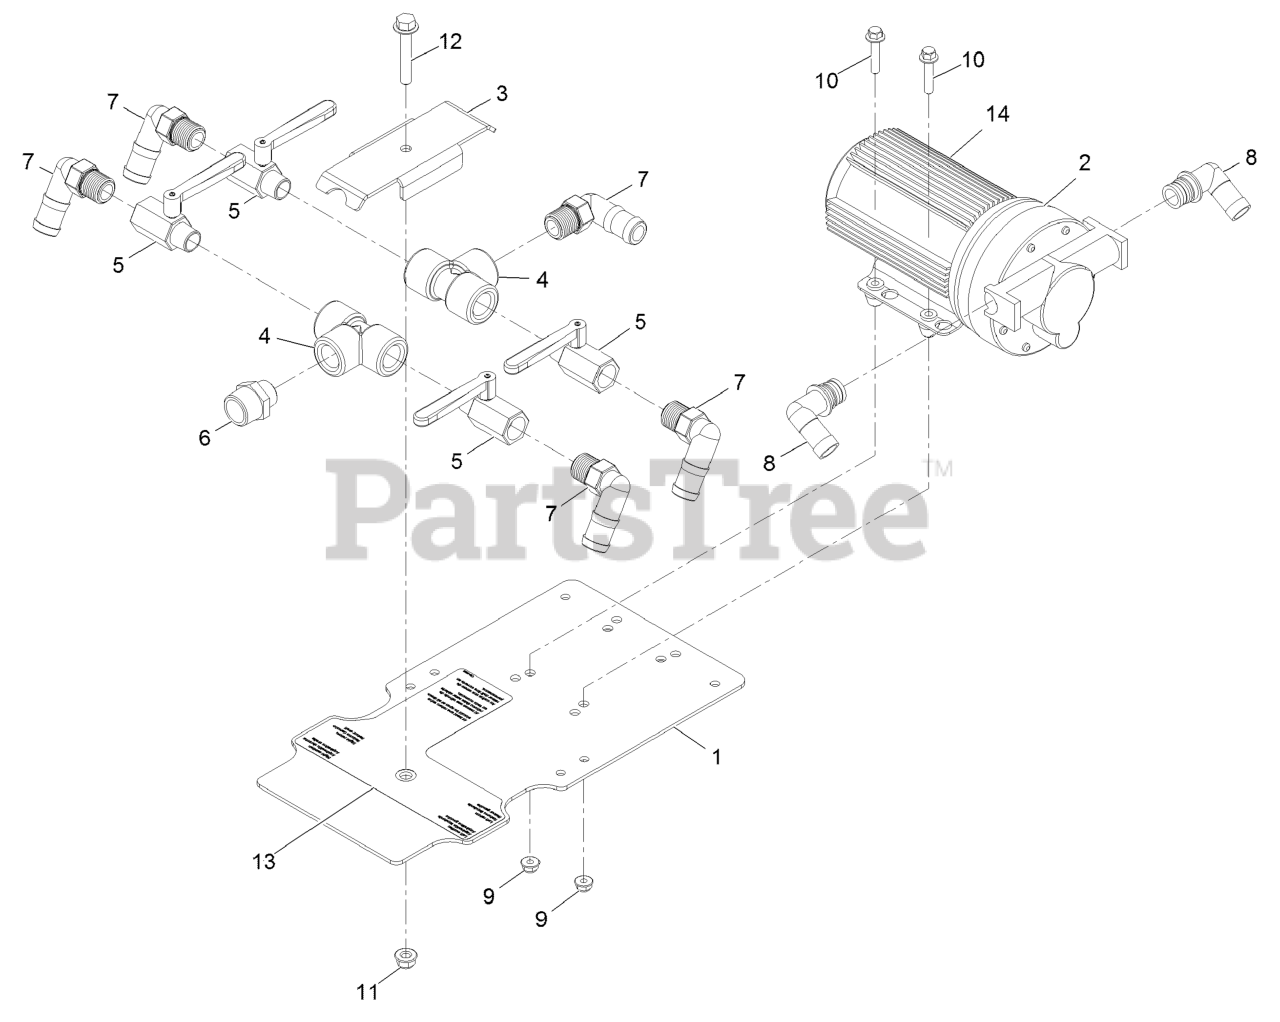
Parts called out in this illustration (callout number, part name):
1	MOUNT-PLATE, LIQUID VALVE
2	PUMP-5.3 GPM
3	PLATE-CLAMP, LIQUID VALVE
5	VALVE-CHROME, 1/2
6	FITTING-NIPPLE
7	ELBOW-90
8	FITTING-ELBOW, 3/4QD X 3/
9	Nut-Hex Flange
10	SCREW-HHF
11	Nut-Hex Flange
12	SCREW-HHF
13	DECAL-VALVE, TANK
14	HEATSINK-3.0""
